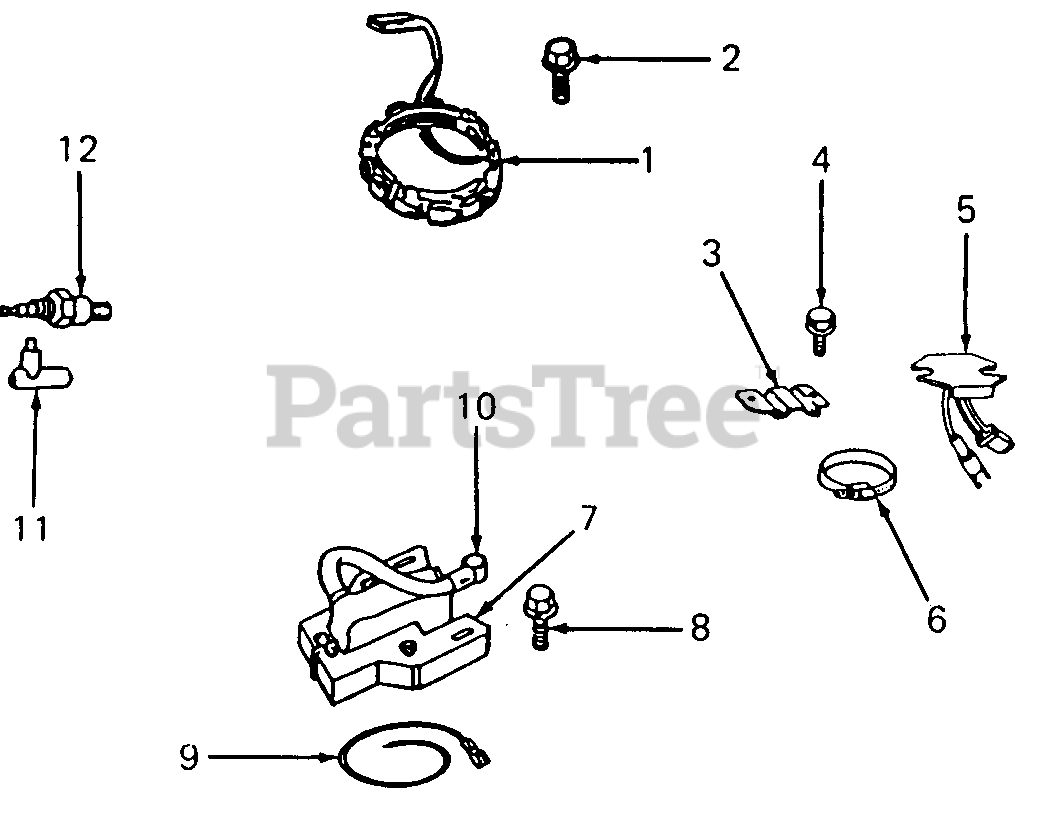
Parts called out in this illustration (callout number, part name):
1	Stator, Alternator
2	Screw, Sem
3	Bracket, Regulator
4	Screw, Regulator
5	Regulator, Alternator
6	Clamp, Regulator
7	Armature, Magneto
8	Screw, Armature Mtg Sem
9	Wire, Ground
10	Terminal, Ignition Cable
11	Elbow, Spark Plug
12	Spark Plug
